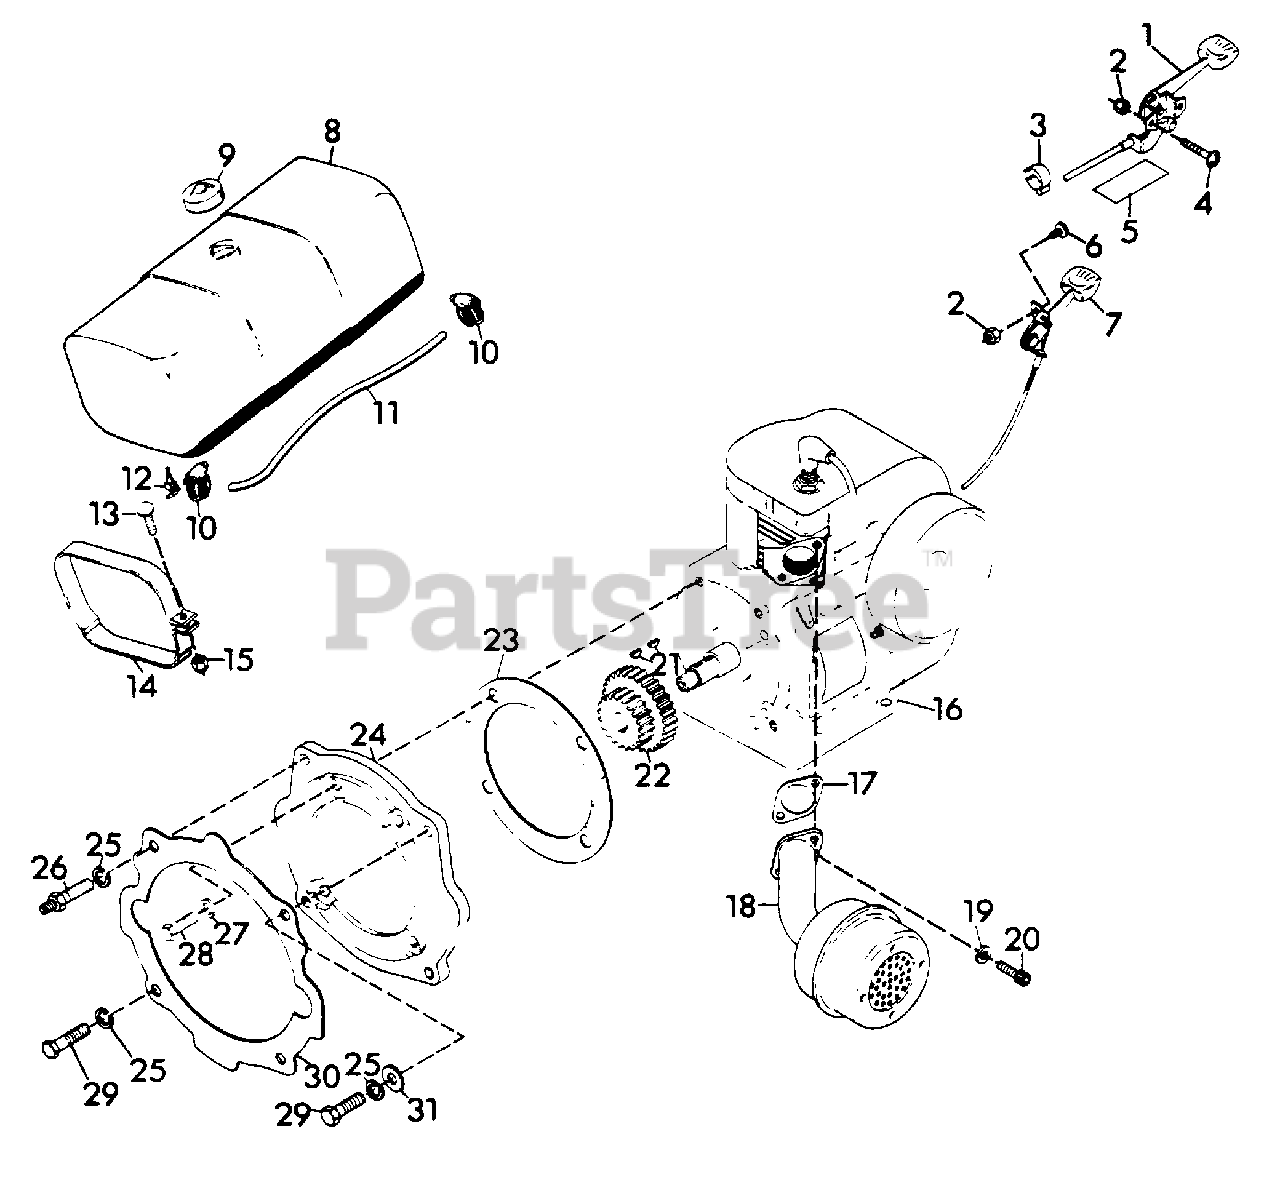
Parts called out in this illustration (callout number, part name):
1	LEVER, THROTTLE CONTROL
2	NUT, LOCK 10-24
3	CLIP, CONDUIT
4	SCREW, MACH. 10-24X1.50 PHD
5	DECAL, THROTTLE
6	SCREW, MACH. 10-24X.50 PHD
7	LEVER, CHOKE CONTROL
8	ASSEMBLY, FUEL TANK
9	CAP, GAS TANK
10	CLAMP, HOSE
11	LINE, FUEL
12	VALVE AND STRAINER
13	BOLT, 1/4-20X1.75 RD.HD.SQ.NECK
14	STRAP, FUEL TANK
15	NUT, LOCK 1/4-20
16	ENGINE, 12 HP ELECTRIC
16	ENGINE, 12 HP MANUAL
16	ENGINE, 10 HP ELECTRIC
16	ENGINE, 8 HP ELECTRIC
16	ENGINE, 8 HP MANUAL
17	GASKET, EXHAUST
18	MUFFLER
19	WASHER, LOCK 5/16 REG.
20	SCREW, CAP 5/16-18X.75 SHD
21	KEY, WOODRUFF 5/32X5/8 HARD #6
22	GEAR, 10/12 DP 21/30 TEETH
23	GASKET, ENGINE TO ADAPTOR
24	ADAPTOR, ENGINE
25	WASHER, LOCK 7/16 SP HEAVY
26	STUD
27	WASHER, LOCK 3/8 SP HEAVY
28	BOLT, HEX 3/8-16X1.00
29	BOLT, HEX 7/16-14X1.25
30	GASKET, CHASSIS TO ADAPTOR
31	WASHER, FLAT .469X.938X.065
